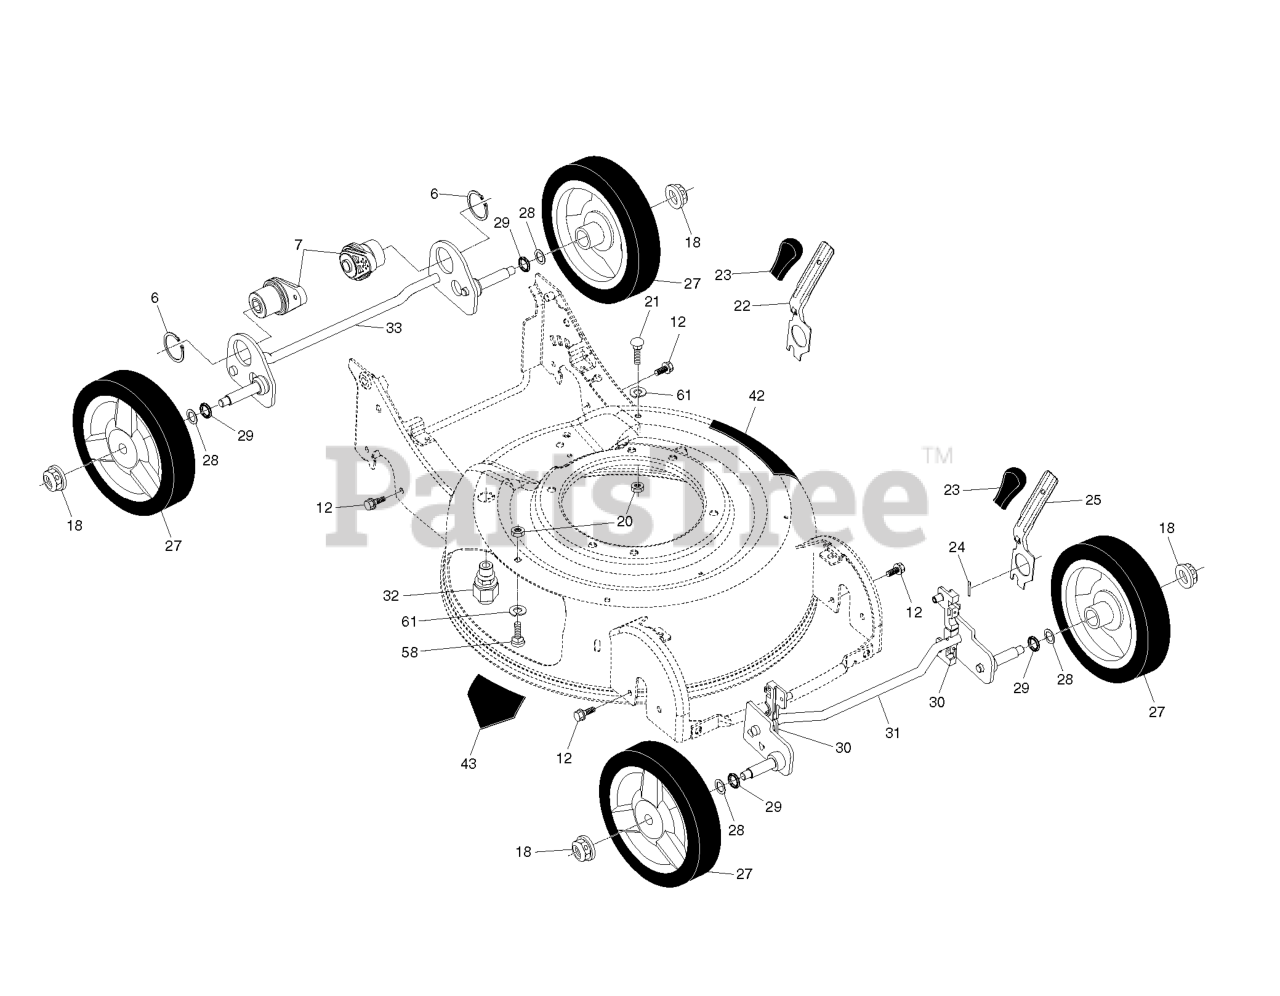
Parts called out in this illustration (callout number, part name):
6	RETAINING RING (2 2)(3 2)
18	NUT.HEX.FLANGE.3/8-16.LO(3 2)
20	NUT, HEX
24	SPRING RETAINER
27	WHEEL & TIRES ASSY, FRONT
28	WASHER.FLAT.1/2
29	O-RING..070X.487.NEOPRENE
30	BUSHING.FRONT.TORQUE.S
33	AXLE.ASM.REAR.45CM.SP.BZP
43	DECAL.INTERNATIONL.CUTFINGER
58	BOLT.CARRIAGE.1/4-20 X 7/8
61	LOCKWASHER
